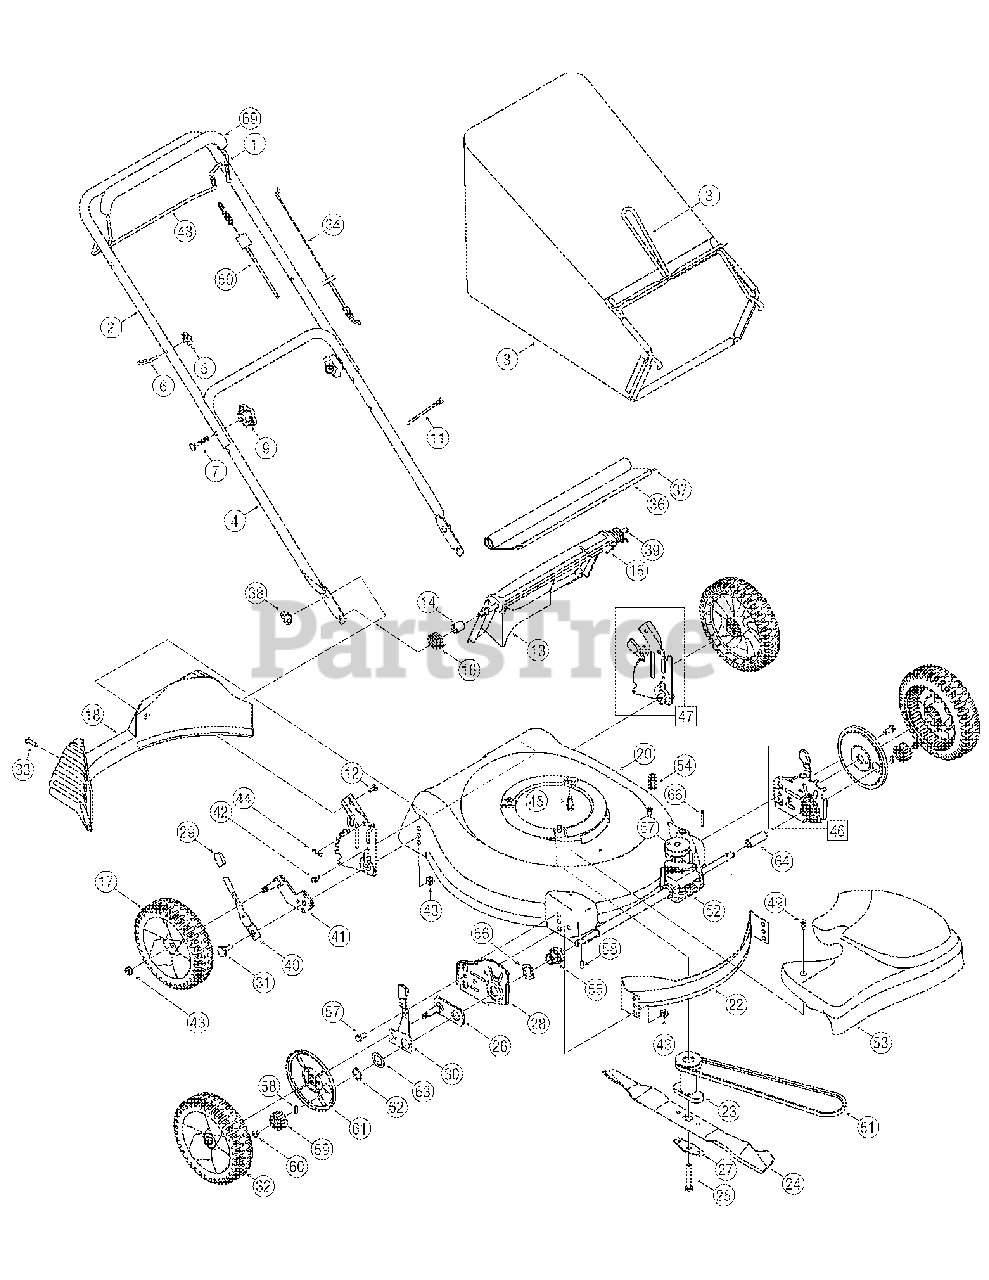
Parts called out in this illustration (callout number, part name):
5	Wing Nut
6	Rope Guide
7	Carriage Bolt, 5/16-18 x 2
8	Grass Bag Assembly
9	Hand Knob
10	Saddle Washer
11	Cable Tie
12	Carriage Bolt ,1/4-20
13	Rear Discharge Door
14	Spacer
15	Torsion Spring - LH
16	Torsion Spring - RH
17	Rear Wheel, 8" x 1.8"
18	Rear Baffle
22	Front Baffle
23	Blade Adapter w/Pulley
24	21" Standard Cut Blade
25	Hex Bolt , 3/8-24 x 2.5
26	Pivot Plate Assembly
27	Blade Bell Support
28	Height Adjustment Plate - RH
28	Height Adjustment Plate - LH
29	Adjustment Lever Knob
30	Front Lever - RH
30	Front Lever - LH
31	Shoulder Screw
32	Front Wheel, 8" x 1.8"
33	Screw, 1/4-15 x 1.250
34	Control Cable - 40.75"
34	Control Cable - 50.56"
36	Trailshield
37	Trailshield Wire
38	Wing Nut, 1/4-20
39	Rear Door Pivot Rod
40	Spring Lever
41	Pivot Arm Assembly - RH
41	Pivot Arm Assembly - LH
42	AB Screw
43	Flange Lock Nut, 3/8-16
44	Hairpin Clip
45	TT Sems Screw, 3/8-16 x 1.00
46	Ht. Adj. Assy. Front - LH
46	Ht. Adj. Assy. Front - RH
47	Rear Handle Bracket Assy. - LH
47	Rear Handle Bracket Assy. - RH
48	Lower Bail Handle
49	Shoulder Screw
50	Drive Cable 51"
51	V-Belt
52	Transmission Assembly
53	Front Drive Cover
54	Belt Tension Spring
55	Bearing Assembly
56	Wave Washer
57	Hex Screw
58	Dowel Pin
59	Gear, 14T - RH
59	Gear, 14T - LH
60	Screw 1/4-20
61	Wheel Dust Cap
62	Snap Ring
63	Washer, 1.5" OD
64	Sleeve Spacer - LH
65	Sleeve Spacer - RH
66	Roll Pin
67	Input Pulley
68	Handle Bracket - RH
68	Handle Bracket - LH
69	Deluxe Bale Cover
